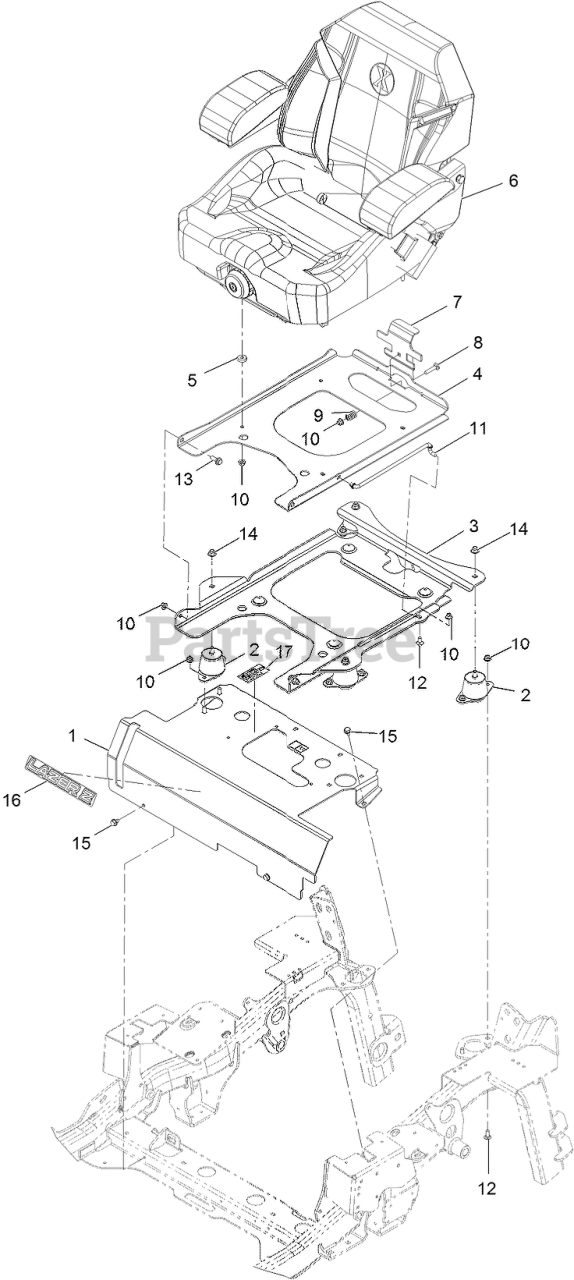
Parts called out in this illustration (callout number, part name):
1	SEAT MOUNT ASM
2	ISOLATOR-SEAT
3	PLATE-SUPPORT, TILT SEAT
4	PLATE-FRAME, SEAT
6	KIT-SUSPENSION SEAT
7	PLATE, SEAT LATCH
8	BOLT-CARR
9	SPRING-COMPRESSION
10	NUT-HF, NI
11	ROD-PROP
12	SCREW-CARR
13	SCREW-SHOULDER
14	NUT-HF, NI
16	DECAL, LAZER MODEL
17	DECAL-TRANS FLUID
